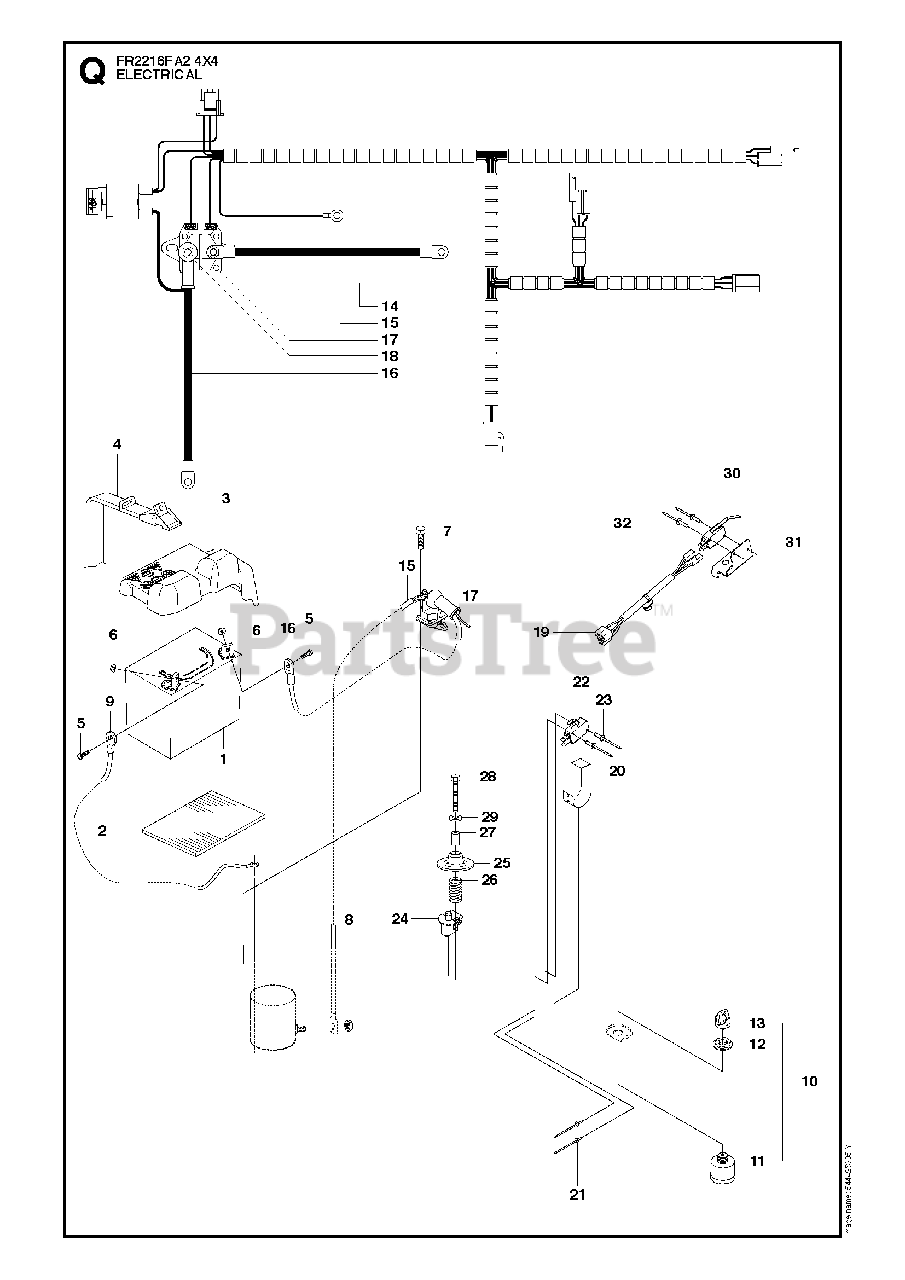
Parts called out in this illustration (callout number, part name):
5	SCREW EHHM
10	IGNITION SWITCH
11	IGNITION SWITCH
12	NUT
13	IGNITION KEY
19	WIRING
27	SPACER TUBE
28	SCREW
29	WASHER BRB 8.4X17
30	MICRO SWITCH
